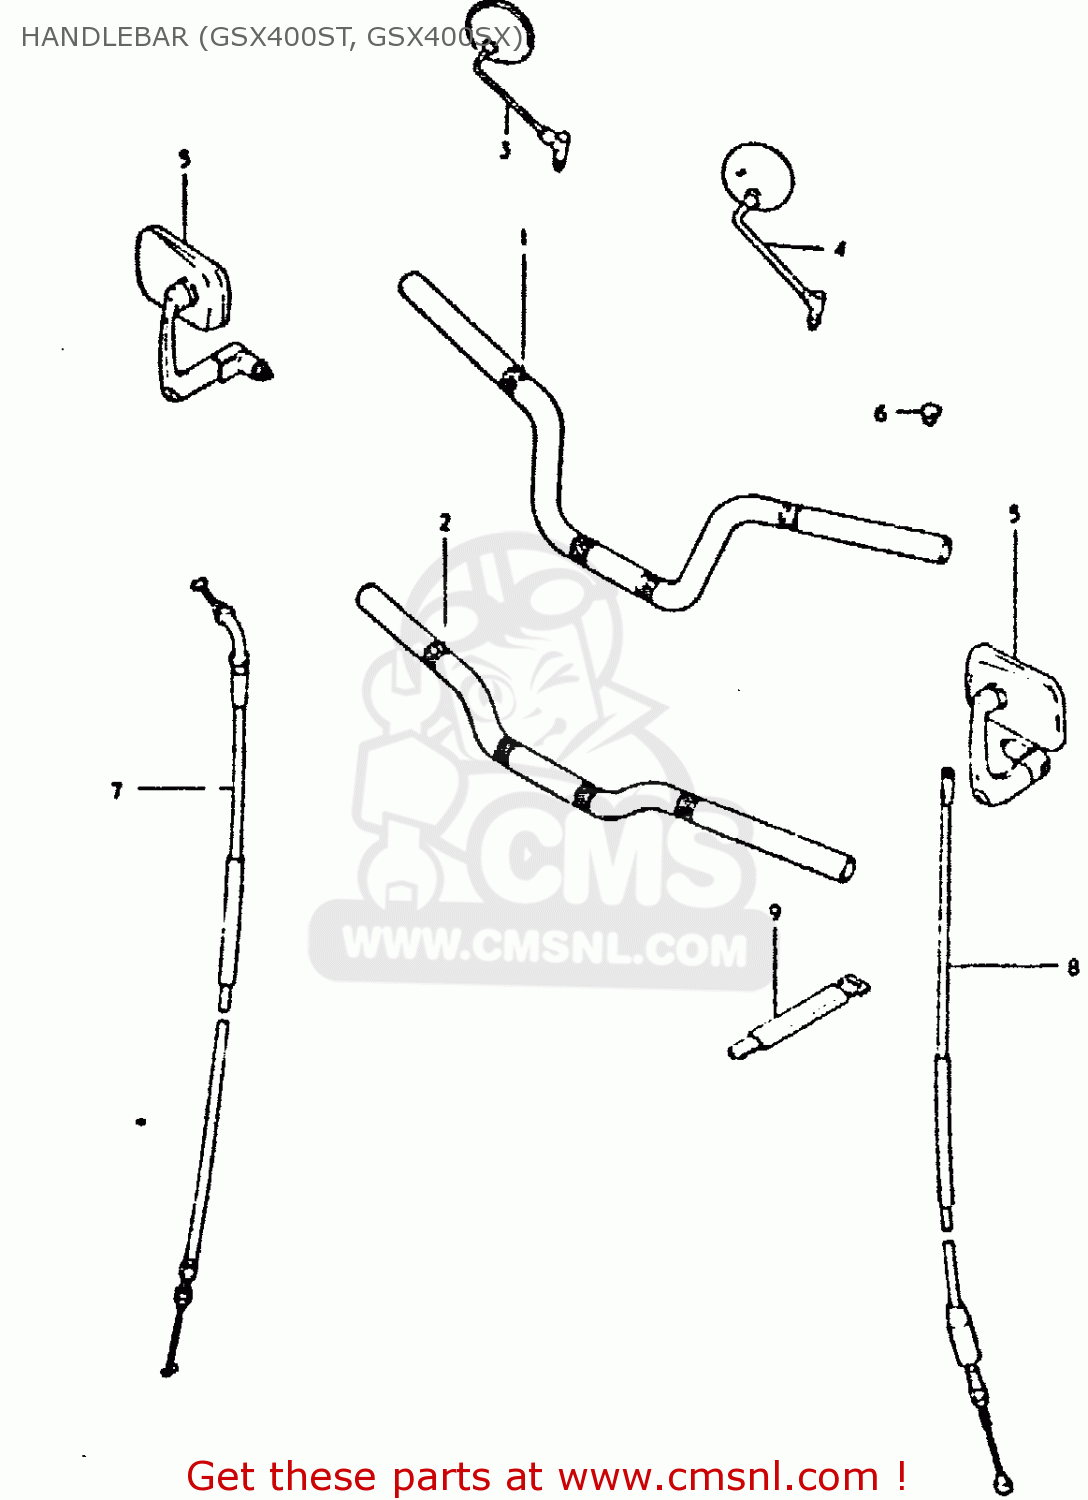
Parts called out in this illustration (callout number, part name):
1	HANDLEBAR
2	HANDLEBAR
3	MIRROR ASSY,RR VIEW
7	CABLE ASSY,CLUTCH
8	CABLE ASSEMBLY,THROTTLE
9	CLAMP
